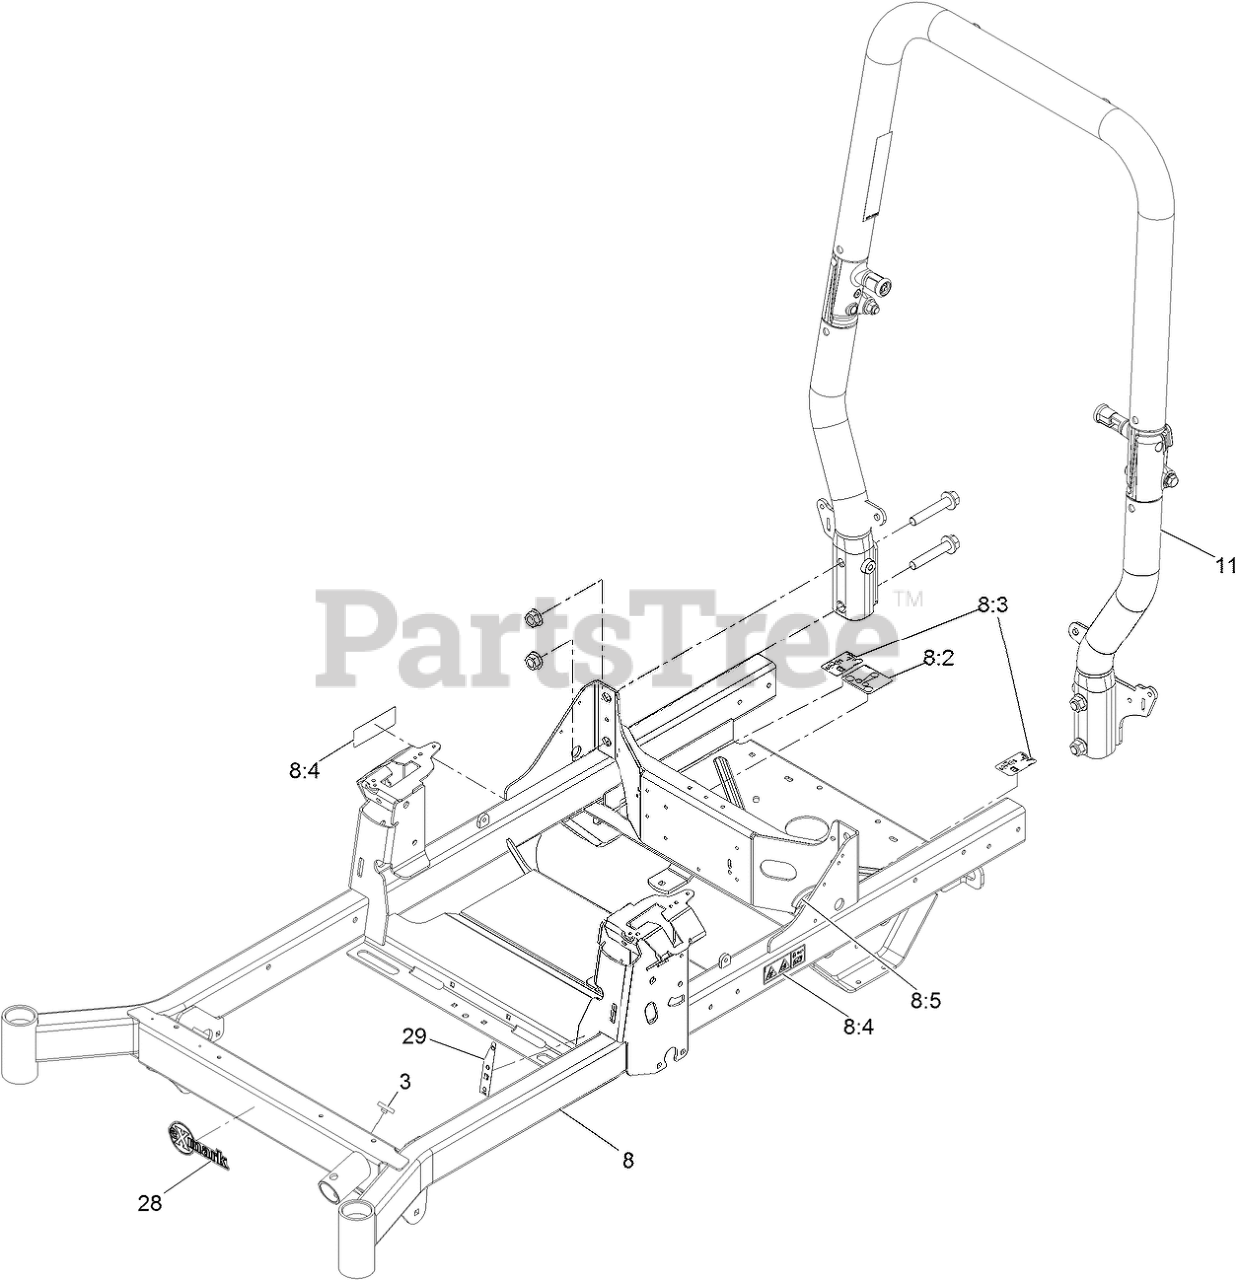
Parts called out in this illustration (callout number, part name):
3	BUMPER-PUSH-IN, RUBBER
8	Suspension Frame ASM
8:2	DECAL-ROUTING, BELT
8:3	DECAL-RELEASE, DRIVE
8:4	DECAL-WARNING
8:5	STRIP-SEAL
11	ASM-ROPS TAPERED
28	DECAL-EXMARK LOGO
29	DECAL-FILL, FUEL
